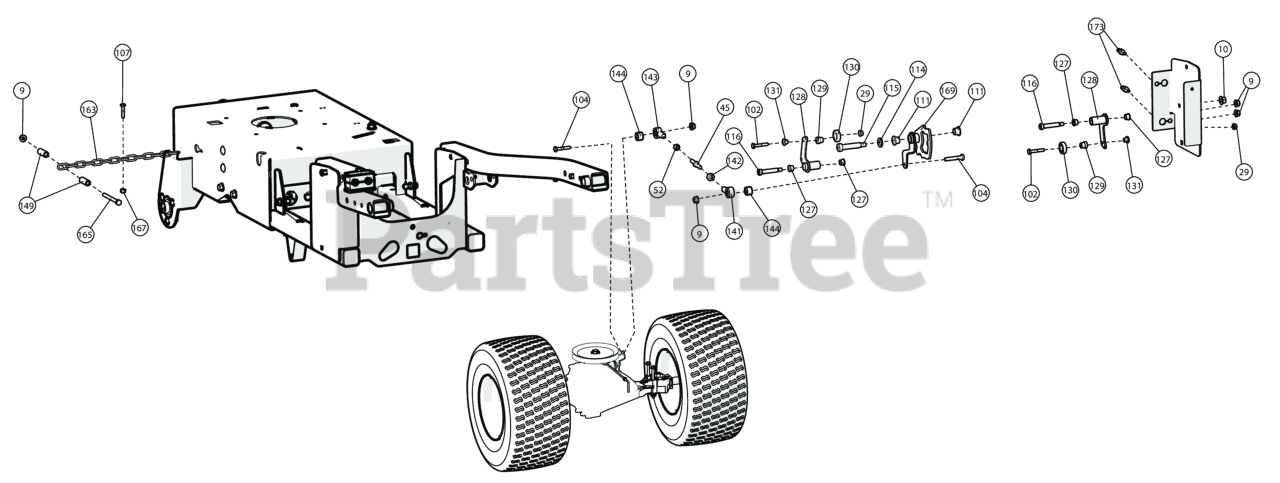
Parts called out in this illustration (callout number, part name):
9	NUT-HEX-NYLK, FLG .3125-18 ZP
10	NUT-HEX-NYLK, FLG .375"-16 ZP
29	NUT-HEX-NYLK, FLG .250"-20 ZP
45	JACKSCREW 5/16"-24 RT AND LFT
52	NUT 5/16"-24 LEFT HAND FIN HEX ZP
102	SCREWCAP 1/4"-20X1 1/2" HCS ZP
104	SCREWCAP 5/16"-18X1 3/4" HCS ZP
107	SCR-CAP, HEX .250"-20 X 1.250" 18-8 SS
111	BUSHING .500" ID
114	WSHR-STL,FLT .500"X.875"X.134" MAB ZP
115	BLT-SLDR,SH.500"X2.00",.375"-16X.63"G8ZP
116	BOLT SHOULDER 3/8" X 1 3/4"
127	BUSHING 3/8 ID X 1/2 OD X 3/8
128	BELLCRANK SPEED CONTROL BC26
129	SPACER. SPEED CONTROL STEPPED PM
130	BEARING 1/2" ID X 1.125 OD
131	SPACER, SPEED CONTROL EYELET PM
141	SPHERICAL ROD END MSF-5
142	NUT-HEX, JAM, .3125"-24 G2 YZ
143	SPHERICAL ROD END FEMALE 5/16"-24 LFT
144	TUBE PIVOT IDLER
149	SPACER - TINE SPROCKET
163	CHAIN, GRADE 30, 13" OAL
165	SCREWCAP 5/16"-18X3 1/2" HCS ZP
167	NUT LOCK 1/4"-20 HEX Z/P
169	CAM, SPEED CONTROL WA
173	CABLE, SPEED CONTROL ASSY RT
